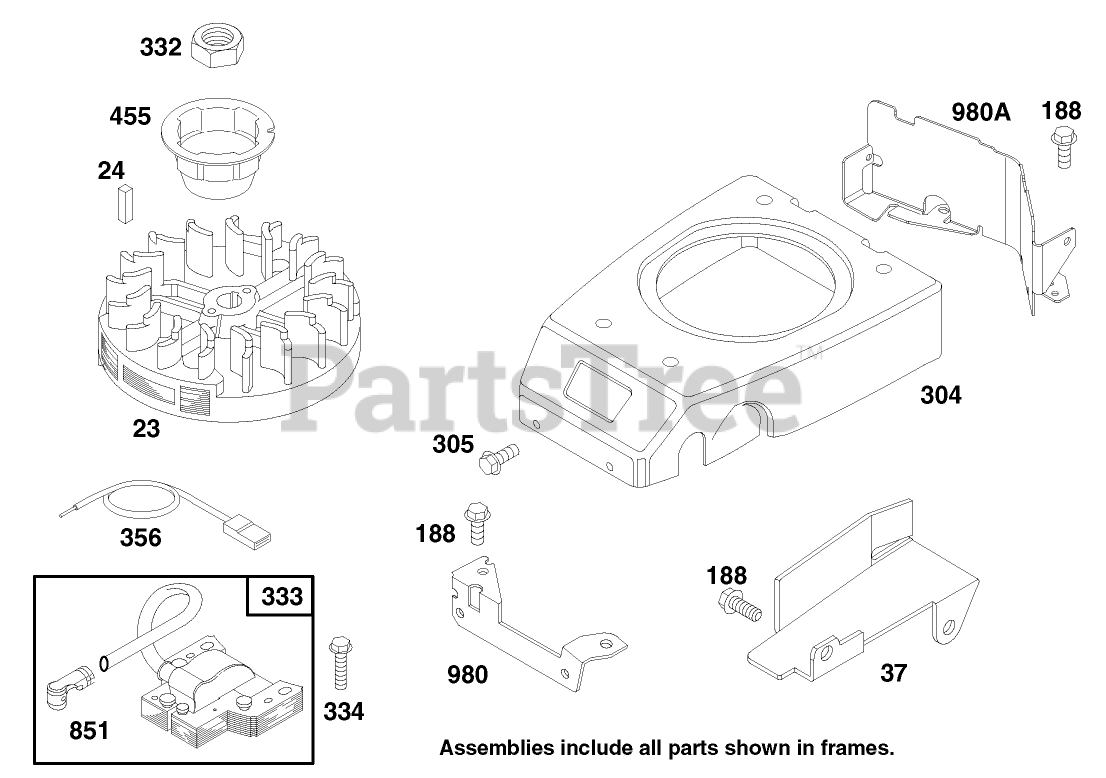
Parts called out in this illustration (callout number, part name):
24	KEY - FLYWHEEL
188	SCREW - HEX HEAD
304	BLOWER HSG ASM
305	SCREW - HEX HEAD
332	NUT - HEXAGON
356	WIRE - GROUND
980A	BLOWER HSG BRACKET
